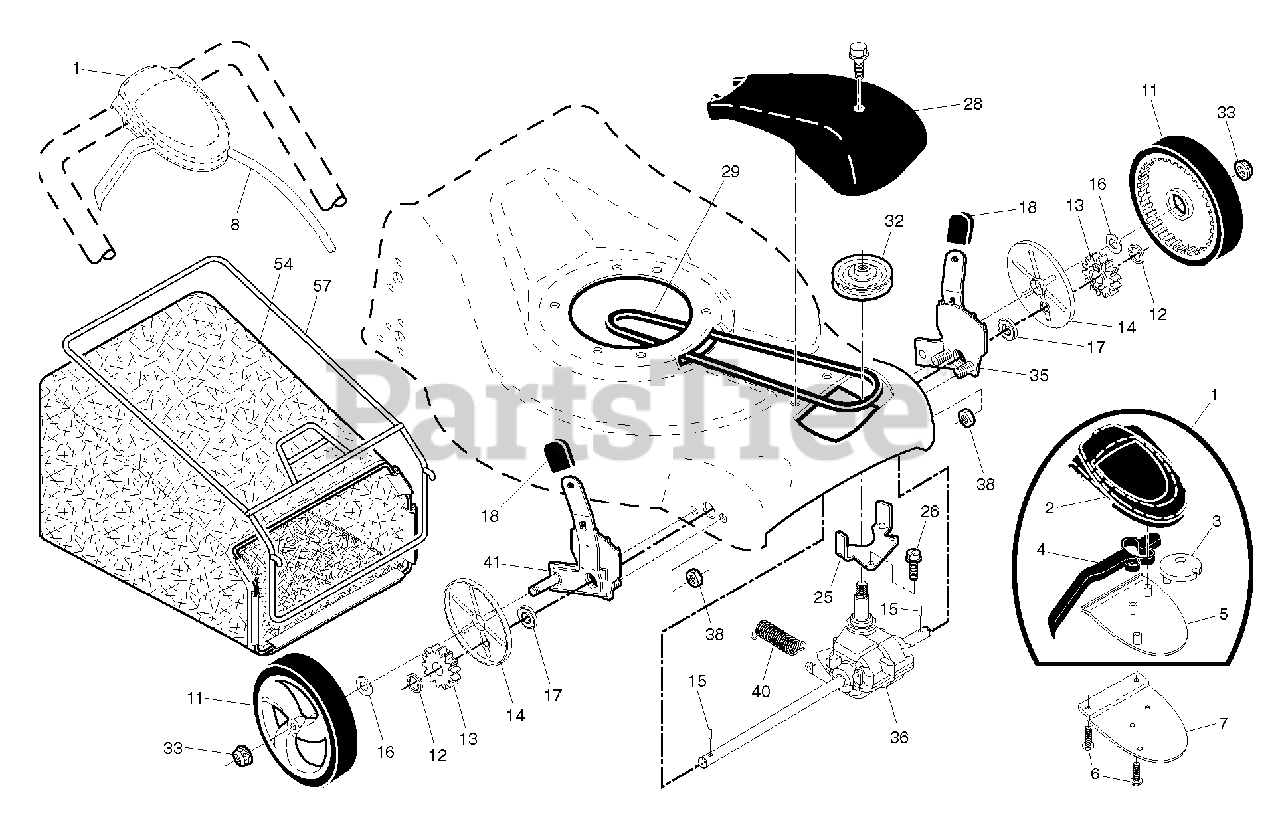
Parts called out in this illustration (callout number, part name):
1	CONTROL.DR.EZ.FGD.SHORT.BK/RED
2	COVER, TOP DRIVE CONTROL
3	PULLEY.CAM.DRIVE.CONTROL.EZ
5	COVER BOTTOM DRIVE CNTRL BLACK
6	SCREW, PHILLIPS HEAD 10 X 5/8
7	BRACKET.DRIVE.CONTROL.MOUNT
8	CABLE ASSEMBLY, DRIVE
11	WHEEL.8X1.75.MAG2.RAD3.GRY
12	E-RING 7/16 RE
13	PINION.14.TEETH.FGD
14	COVER.DUST.WHEEL
17	BEARING
25	BRACKET.BELT.GUIDE.22+FGD.BZP
29	BELT.DRIVE.FG
32	RP PULLEY.DRIVE.EZ
33	NUT.HEX.FLANGE.3/8-16.LOCKNUT
35	RP KIT, WHEEL ADJUSTER, LH
36	TRANSMISSION.21.FGD.HT*SUBS/2*
38	LOCKNUT
41	KIT, WHEEL ADJUSTER, RH
57	FRAME.GBAG.21.FWGD
